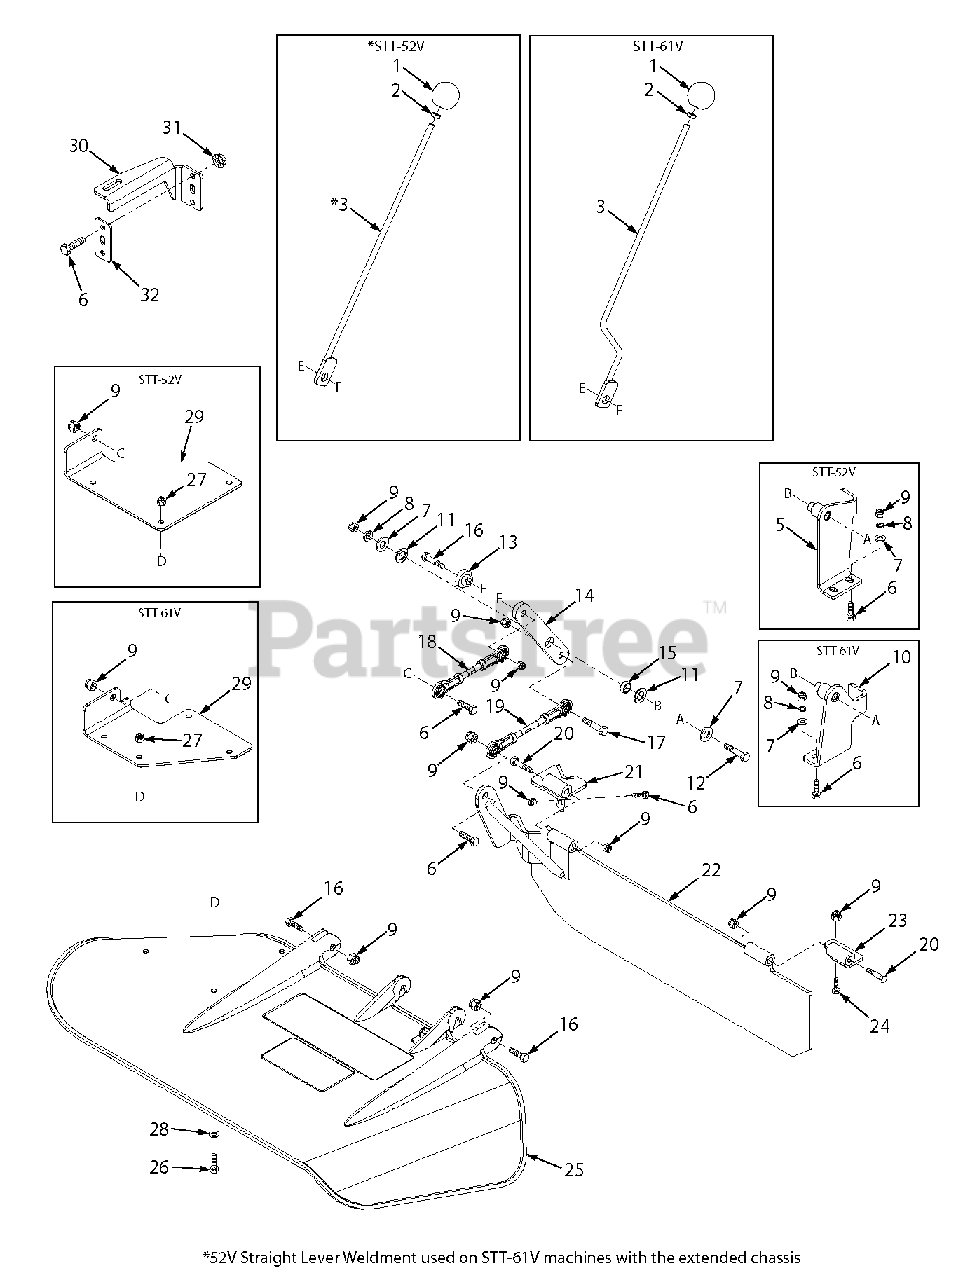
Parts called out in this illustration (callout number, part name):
1	Knob, OCDC Lever
2	Nut, 3/8-16 Jam
3	Lever Weldment, OCDC - Straight
4	Lever Weldment, OCDC - Curved
5	Pivot Weldment
6	Bolt, Hex Head 5/16-18 x 1"
7	Flatwasher, 5/16-.375 x .875 x .083
8	Lockwasher, 5/16" Spring
9	Nut, Elastic Stop 5/16-18
10	Pivot Weldment, 61V
11	Washer, Thrust
12	Bolt, Hex Head 5/16-18 x 2"
13	Bushing
14	Plate, Pivot Arm
15	Bearing
16	Bolt, Hex Head 5/16-18 x 1-3/4"
17	Bolt, Hex Head 5/16-18 x 1-1/4"
18	Linkage Assembly, Discharge Chute
19	Linkage Assemlby, Block-Off Plate
19	Linkage Assembly, Block-Off Plate
20	Bolt, Hex Head 5/16-18 x 3-1/2"
21	Hinge Weldment, Rear
22	Block-Off Plate Weldment,
22	Block-Off Plate Weldment
23	Hinge Weldment, Front
24	Bolt, Head Head 5/16-18 x 3/4"
25	Discharge Chute Assembly
26	Bolt, Hex Head 1/4-20 x 3/4"
27	Nut, Elastic Stop 1/4-20
28	Flatwasher, 1/4-.312 x .750 x .065
29	Plate, Discharge Chute
30	Bracket, OCDC Lever
31	Nut, Serrated Flange 5/16-18
32	Bracket, Mount
